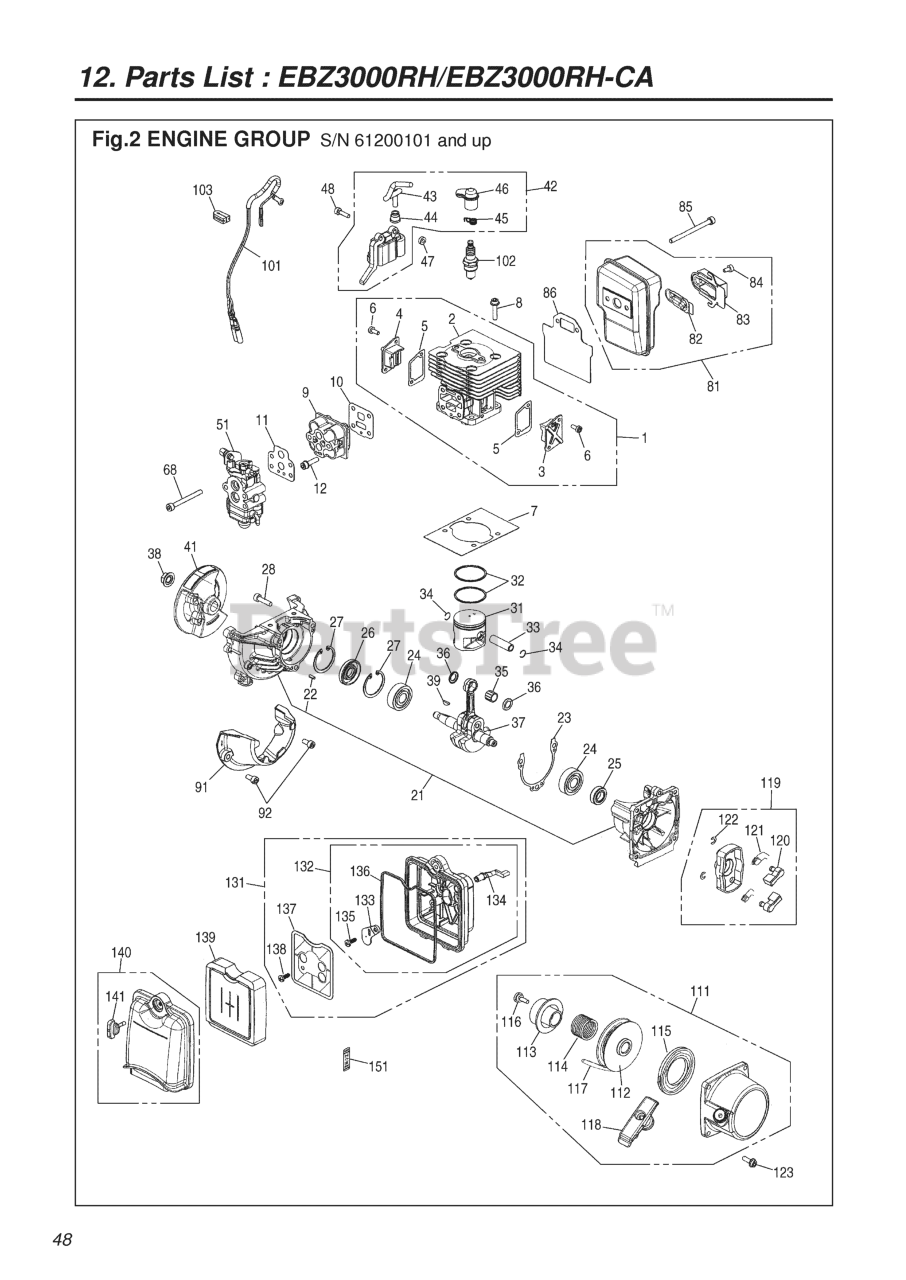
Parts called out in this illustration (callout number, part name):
1	CYLINDER COMP
2	CYLINDER
3	COVER, TR(S)
4	COVER, TR(F)
5	GASKET, TR
6	BOLT
7	GASKET, BASE
8	BOLT
9	INSULATOR
10	GASKET, INSU
11	GASKET
12	BOLT (RPLS 2850-14220)
21	CRANKCASE-C
22	PIN
23	GASKET, CASE
24	BEARING
25	SEAL
26	SEAL
27	RING, SNAP, M32 x 1.2
28	BOLT (RPLS 2850-14220)
31	PISTON
32	RING
34	RING, SNAP
35	BEARING
36	WASHER (RPLS 3310-41341)
37	CRANKSHAFT COMP
39	KEY
42	COIL ASSY
44	CAP
45	SPRING
47	SPACER (RPLS -71260)
48	BOLT TORX
51	CARBURETOR ASSY
68	BOLT
81	MUFFLER
82	ARRESTER
84	Bolt
85	BOLT
86	GASKET
92	BOLT
101	CORD COMP
102	SPARK PLUG (CMR7H)
103	GROMMET
111	RECOIL ASSY
112	REEL
113	PLATE, CAM
114	SPRING, DAMPER
115	SPRING, SPIRAL
116	SCREW
117	ROPE
118	KNOB (RPLS -75420)
119	PULLEY ASSY
120	RATCHET
121	SPRING
122	E-RING
123	BOLT, TORX
131	BODY & SCREEN
132	BODY ASSY
133	PLATE, CHOKE
134	LEVER
135	SCREW
136	PACKING
137	SCREEN (REPLACES -83K1)
138	SCREW
139	ELEMENT
140	COVER ASSY
141	KNOB (RPLS -82220)
151	LABEL, CHOKE
